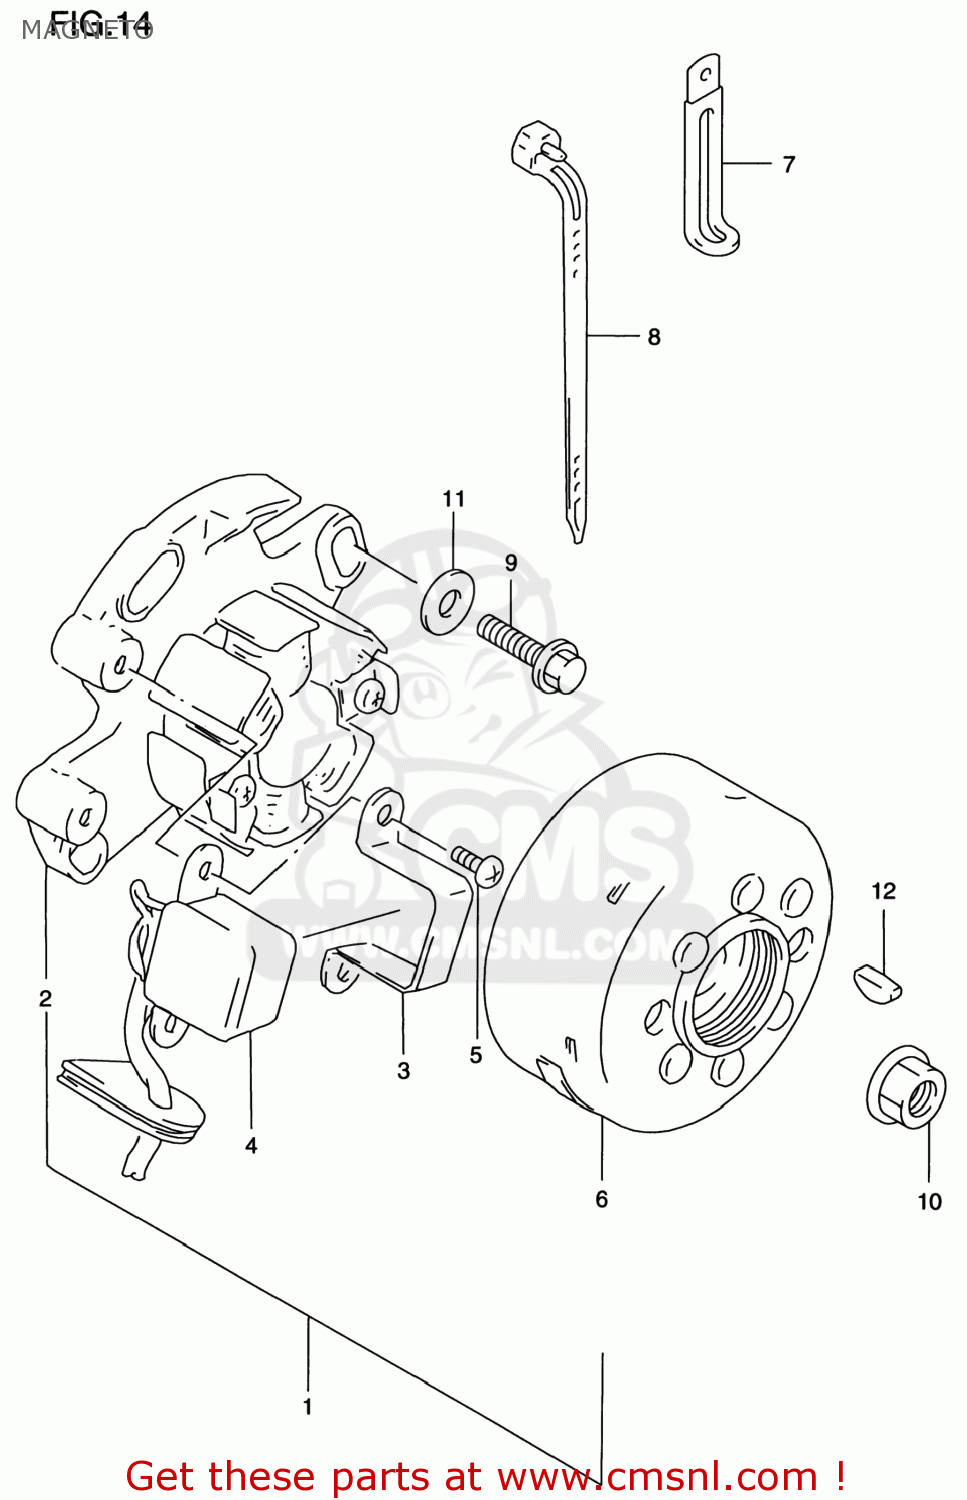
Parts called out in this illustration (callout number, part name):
1	MAGNETO ASSEMBLY
2	STARTER ASSY
3	HOLDER,PICK UP COIL
4	COIL,PULSER
5	SCREW
6	ROTOR
7	CLAMP(L:65)
8	CLAMP(L:165)
9	SCREW
10	NUT
11	WASHER
12	KEY
